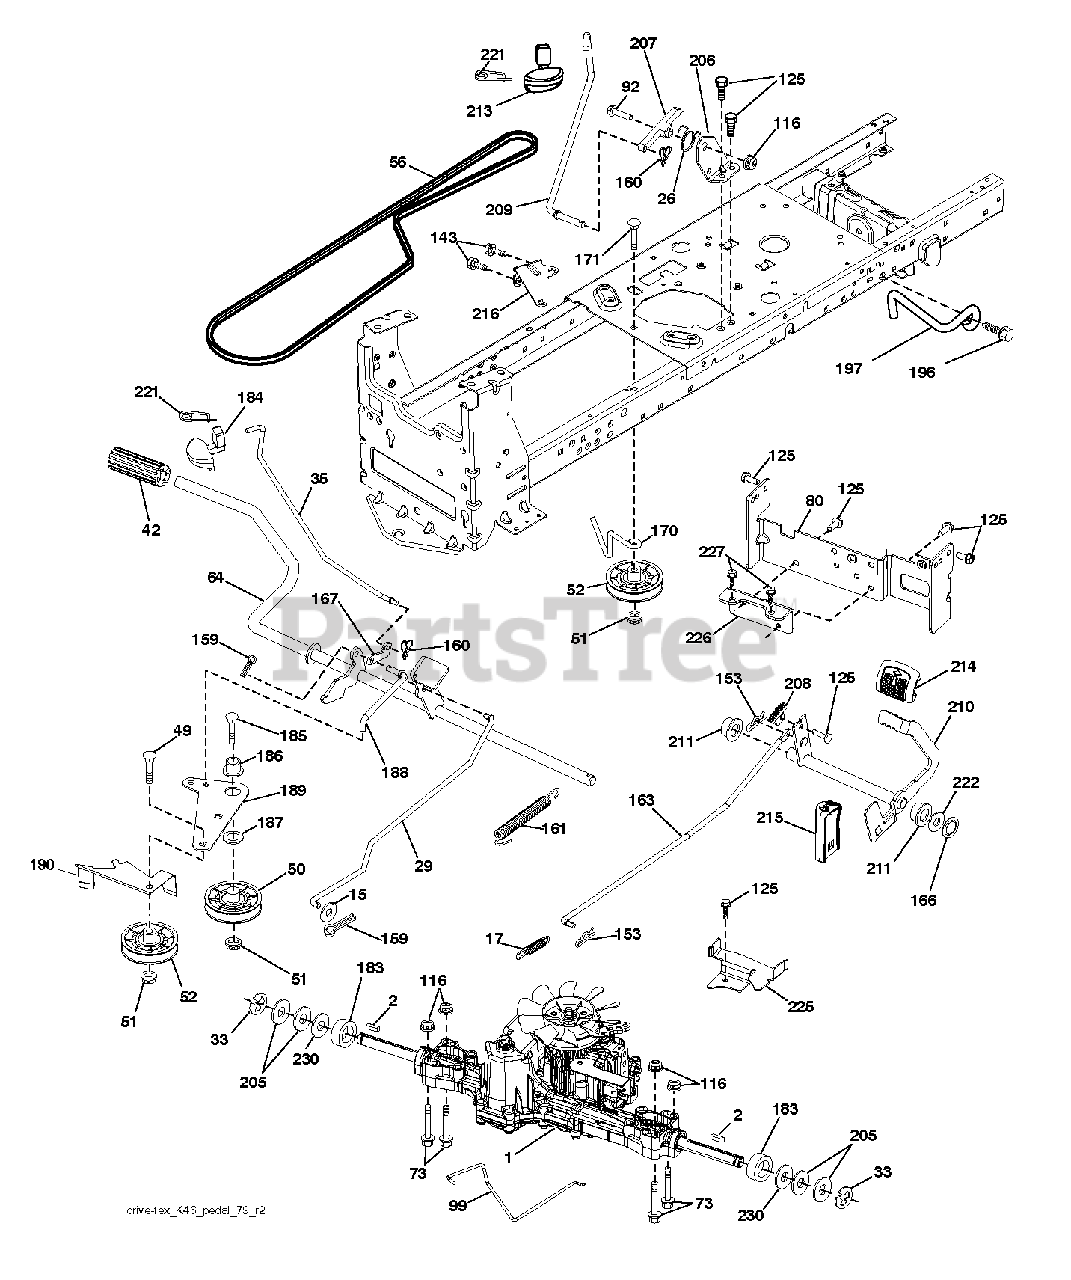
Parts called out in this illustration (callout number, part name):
2	SQUARE KEY
15	WASHER
17	SPRING, BREAK
26	SPRING.RETURN.CRUISE
29	ROD.BRAKE.K46
33	E-RING LT
35	ROD.BRKAE.PARKING.STEALTH
42	PEDAL COVER T
50	IDLER.FLAT.910.OFFSET
52	IDLER.V-GROOVE.910.OFFSET
64	SHAFT.ASM.PEDAL.BRK.CN
99	ROD.SPRING.BYPASS.K46.LT.Z
116	NUT LOCK HEX FLANGE 5/16-18
125	SCREW
143	SCREW LT
159	COTTER PIN
160	RETAINER CLIP
161	SPRING, RETURN LT
166	NUT.PUSH.625
167	LATCH BRAKE PARKING
170	KEEPER.V-IDLER.CENTER.
183	SPACER AXLE
186	SPACER.RETAINER
188	LINK.CLUTCH.GROUND DRI
189	BELLCRANK.GRDDRIVE.NST
190	KEEPER.BELLCRANK.DRIVE
196	SCREW 3/8-16X1
197	LINK.CLUTCH.ANIT-ROTAT
206	BRKT.MOUNT.LATCH.CRUIS
207	LATCH.CONTROL.CRUISE
208	GEAR.SECTOR.CONTROL.CR
209	ROD.CONTROL.CRUISE.STE
210	ROCKER.ASM.PEDAL.CONTR
211	BEARING RER
213	KNOB.CONTROL.CRUISE
214	PAD PEDAL FORWARD
215	PEDAL.REVERSE.TEX.GT.4
216	BRKT.PULLEY.IDLER.WTEX
221	RETAINER.SPRING.CLIP.H
222	WASHER 21/32 X 1-1/4 X 10 GA.
225	KEEPER.BELT.TRANSAXLE.
226	BRACKET MOUNT TORQUE
